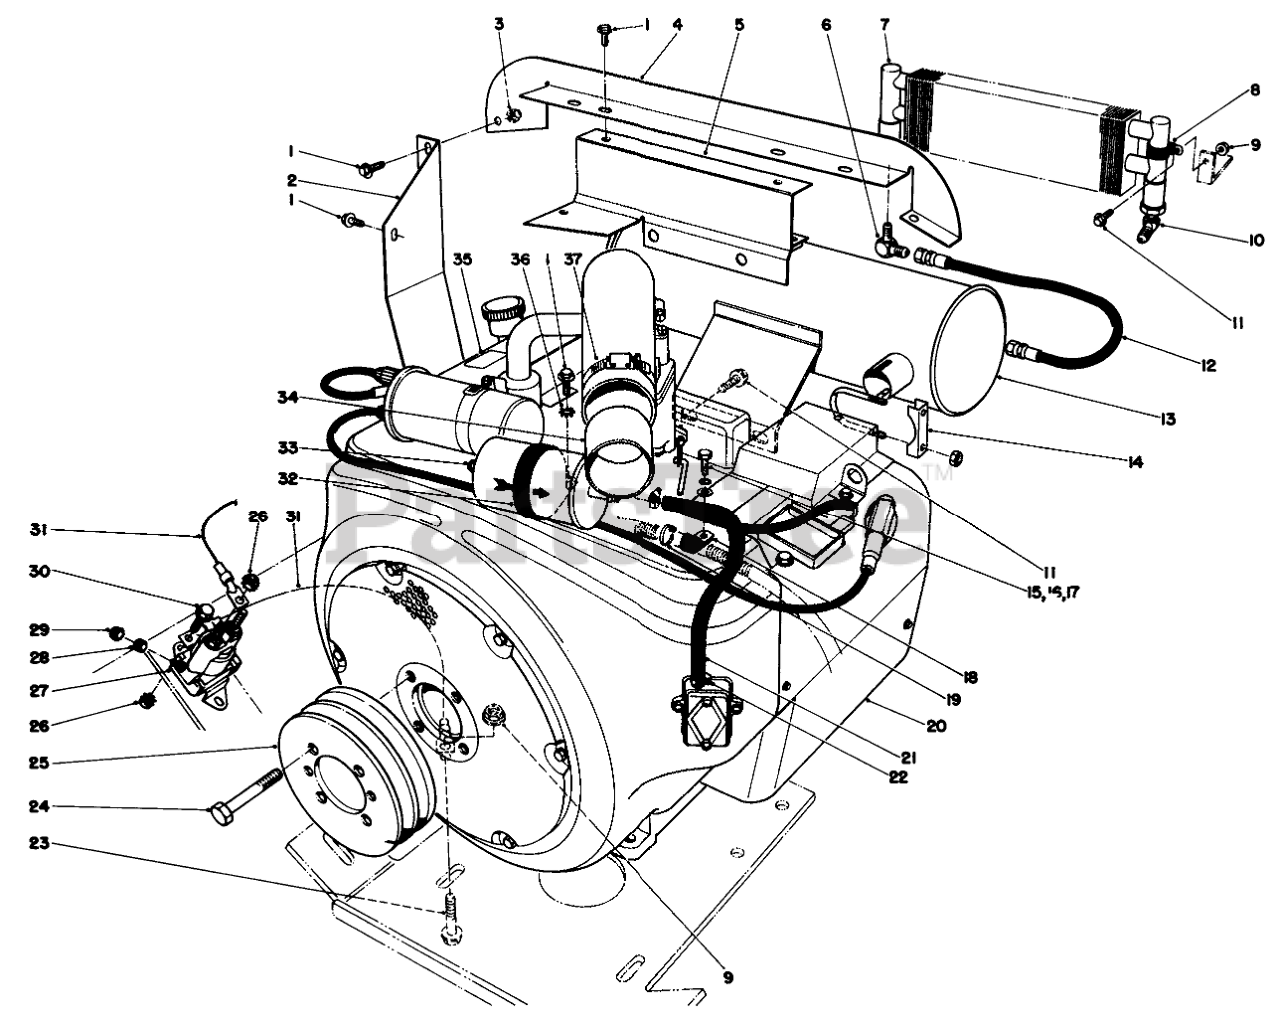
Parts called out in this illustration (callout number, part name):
1	SCREW-HHF
2	Shield-Heat
3	NUT-LOCK, NI
4	Shroud-Engine
5	Bracket-Shield Support
6	90DEG JIC FITTING
7	OIL COOLER
8	CLAMP-R
9	NUT-HHF, WHIZ
10	ELBOW
11	SCREW-HHF
12	OIL HOSE ASM
13	Muffler
14	MUFFLER CLAMP
15	SCREW-HH
16	WASHER-LOCK
17	WASHER-FLAT
18	CLAMP-R
19	Strap
20	Engine (Onan Model No. B48G-GA020 Type No. 4139F
21	FUEL LINE
22	CLAMP-HOSE
23	SCREW-HHF
24	SCREW-HH
25	Pulley-Engine
26	NUT-KEPS
27	Solenoid
28	NUT-HEX
29	NUT-KEPS
30	SCREW-HHF
31	WIRE ASM
32	1.875 ID HOSE CLAMP
33	FiIter Gas
34	AIR CLEANER ADAPTER
35	SERVICE DECAL
36	WASHER-LOCK
37	CLAMP-HOSE
